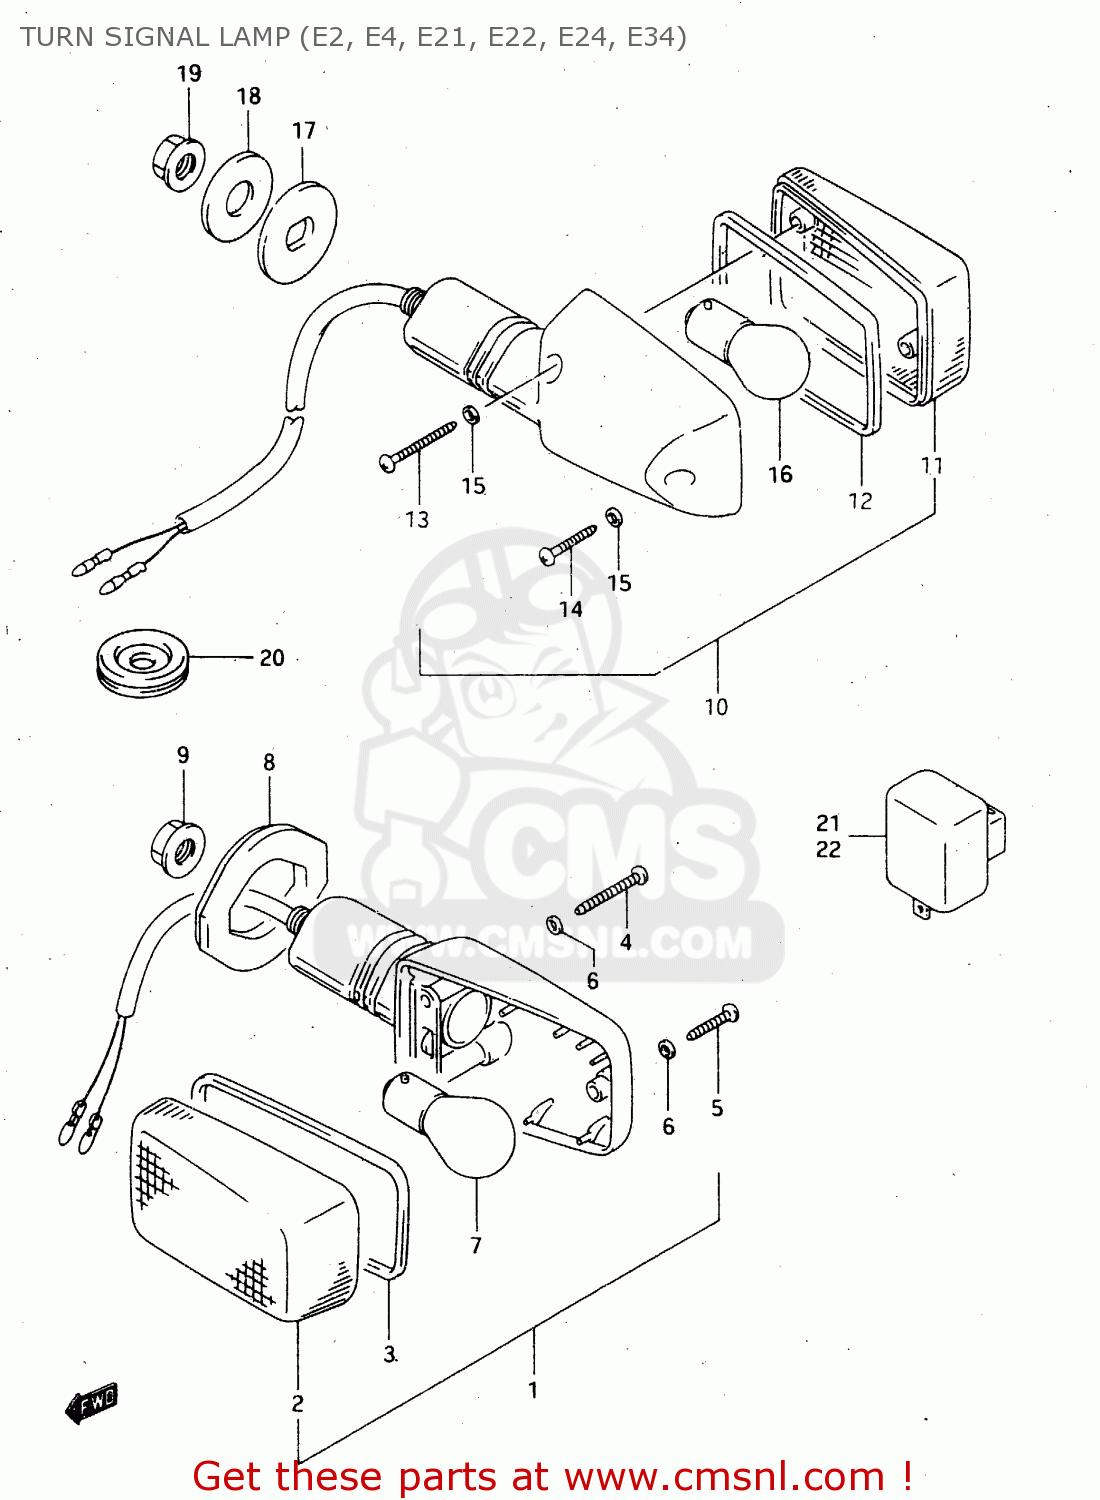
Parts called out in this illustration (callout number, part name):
1	LAMP ASSY,FR TURN SIGNAL
2	LENS
3	GASKET (NAS)
4	SCREW(3X30)
5	SCREW
6	GASKET (NAS)
7	BULB(12V21W)
8	GROMMET
9	NUT
10	LAMP ASSY,RR TURNSIGNAL
11	LENS
12	GASKET (NAS)
13	SCREW(3X30)
14	SCREW
15	GASKET (NAS)
16	BULB(12V21W)
17	SPACER,RR TURNSIGNAL
18	WASHER(10.5X30X3.2)
19	NUT
20	GROMMET
21	RELAY ASSY,TURNSIGNAL
22	RELAY ASSY,TUR
